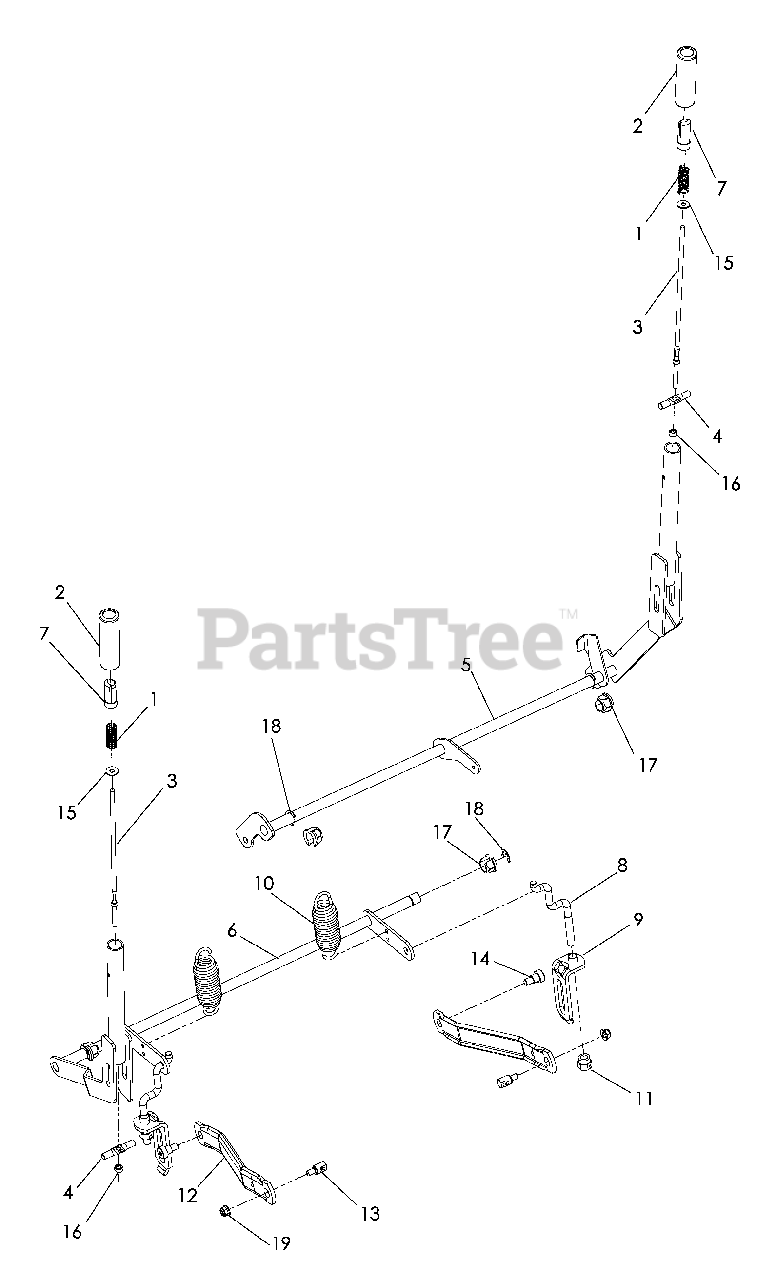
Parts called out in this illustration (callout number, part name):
1	SPRING, COMPRESSION
2	GRIP, HANDLE
3	ROD, HANDLE RELEASE
4	ROD, LATCH RELEASE
5	SHAFT, BRAKE
6	SHAFT, LIFT
7	BUTTON, PUSH
8	LINK, REAR SUSPENSION
9	BRACKET, CENTERING LNK
11	NUT, LIFT LINK
12	ARM, SUSPENSION RR
13	STUD, w/ANTI- ROTATE
14	BOLT 3/8-16 x 3/8 SKT HD
15	WASHER ¼ FLAT
16	NUT ¼-20 HEX NYLOC
17	PLASTIC NUT
19	NUT 5/16-18 FLANGE NYLOC
